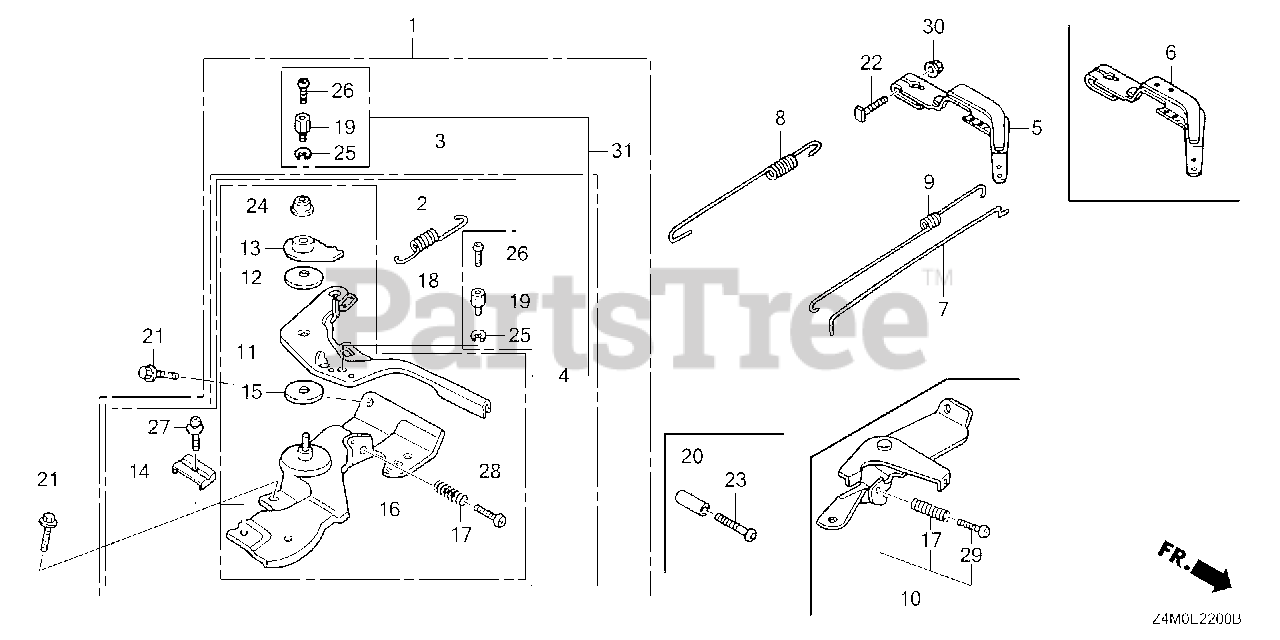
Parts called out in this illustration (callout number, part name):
3	CONTROL ASSY. (REMOTE/INTERNAL)
5	ARM, GOVERNOR
7	ROD, GOVERNOR
8	SPRING, GOVERNOR
9	SPRING, THROTTLE RETURN
11	LEVER, CONTROL
12	SPRING, LEVER
13	WASHER, CONTROL LEVER
14	HOLDER, CABLE
15	SPACER, CONTROL LEVER
16	BASE, CONTROL
17	SPRING, CONTROL ADJUSTING Use from Engine SN 2327377.
18	SPRING, CABLE RETURN
19	HOLDER, WIRE
20	COLLAR, STOPPER
21	BOLT, FLANGE (6X12) (CT200)
22	BOLT, GOVERNOR ARM
23	SCREW, RECESSED (5X25)
24	NUT, SELF-LOCK (6MM)
25	CIRCLIP (5MM) Use from Engine SN 2327377.
26	SCREW, PAN (4X6)
27	SCREW, PAN (5X16)
28	SCREW, PAN (5X25)
30	NUT, FLANGE (6MM)
